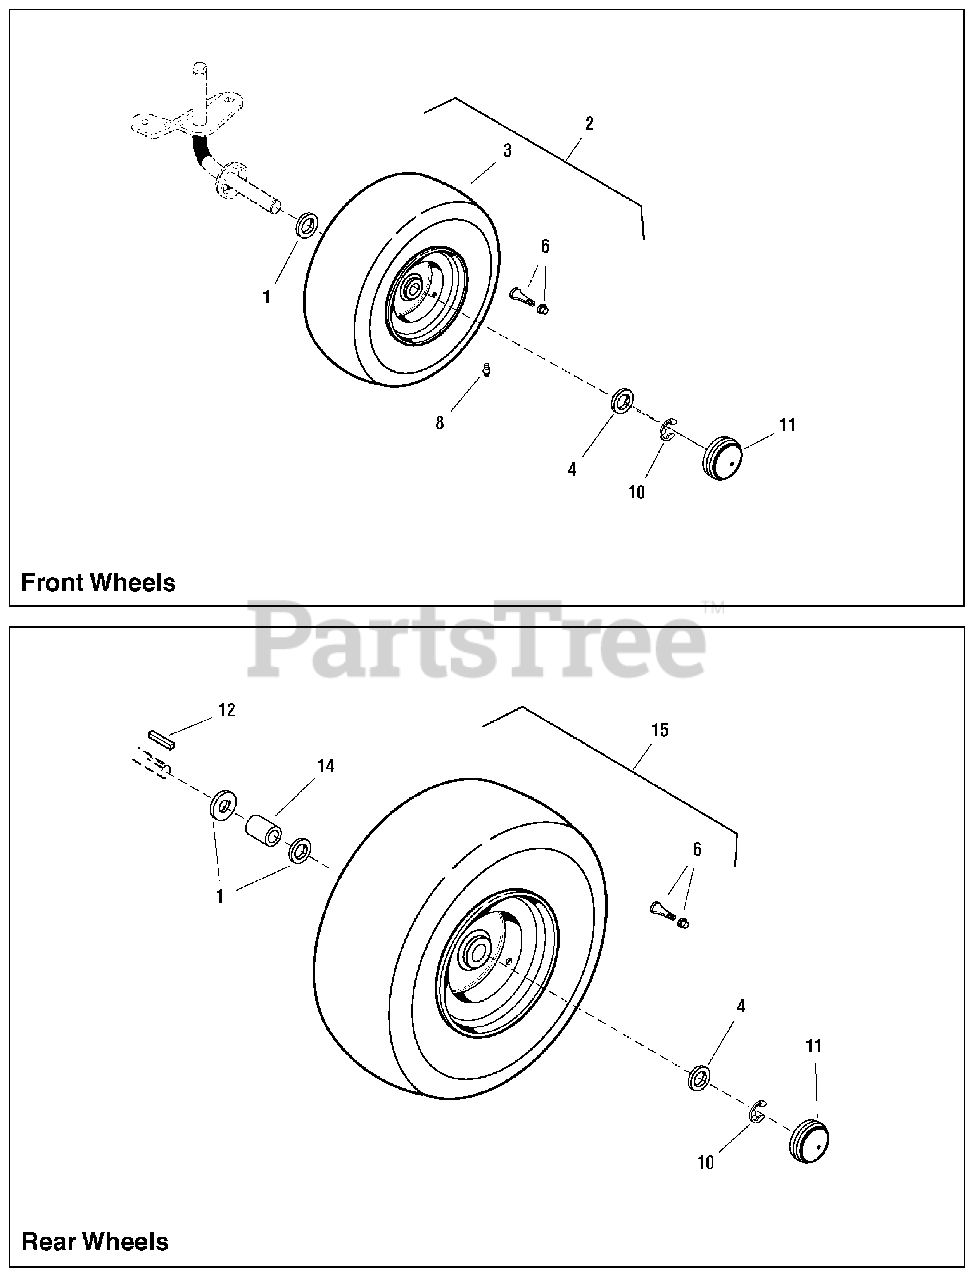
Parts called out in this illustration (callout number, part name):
1	WASHER, Flat, 3/4 x 1-1/4 OD
2	WHEEL&TIRE ASSEMBLY, Front
3	TIRE, 15 X 6.00 - 6 Turf Rider
4	WASHER, Flat, .765 x 1.862
6	VALVE STEM AND CAP
8	FITTING, Lube
10	E-RING
11	HUB CAP
12	KEY, Square, 3/16
15	WHEEL & TIRE ASSEMBLY, 20X10.0-8, Rear
